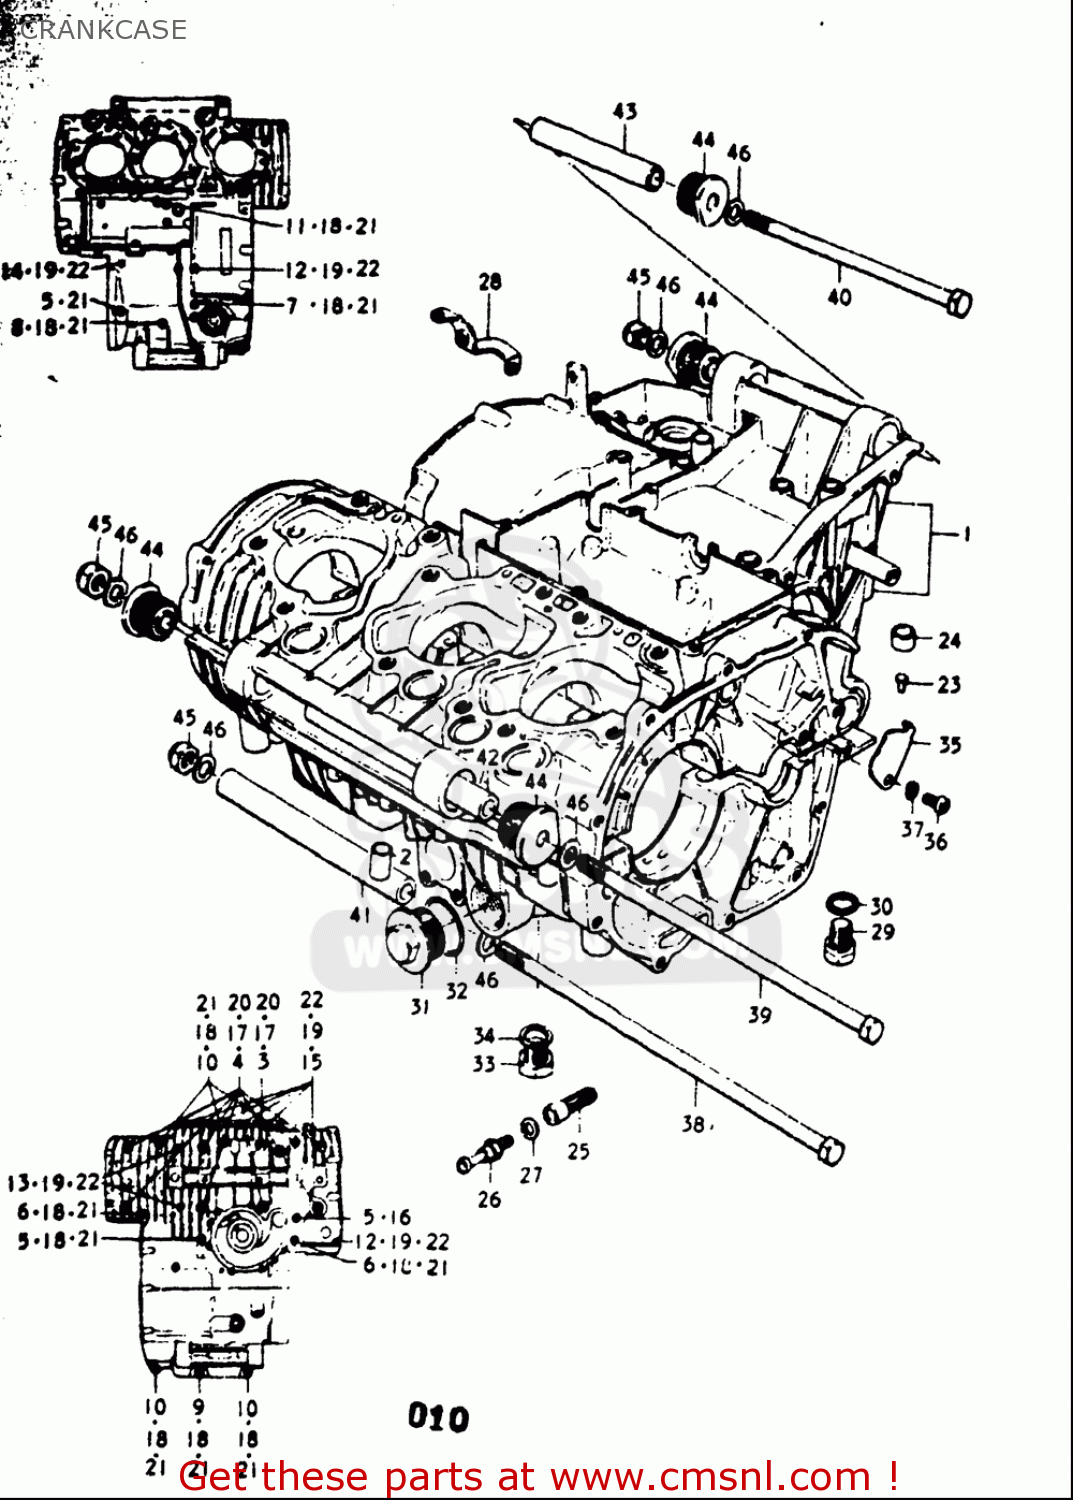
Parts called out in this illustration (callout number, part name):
2	PIN
3	BOLT
6	BOLT
7	BOLT
8	BOLT
9	BOLT
10	BOLT
11	BOLT
12	BOLT 6X110
13	BOLT 6X95 HEXAG
14	BOLT
15	BOLT(6X35)
16	GASKET(8.2X14X1) (NAS)
17	WASHER
18	WASHER
19	WASHER
20	WASHER,LOCK
21	WASHER,LOCK
22	WASHER,LOCK
23	RIVET
24	BUSHING
26	CHECK VALVE,SRIS
27	GASKET(8.2X14X1) (NAS)
29	PLUG
30	GASKET(14X19.2X2) (NAS)
32	O RING(D:1.9,ID:32.7)
33	PLUG(MAGNETO)
34	GASKET(14X19.2X2) (NAS)
36	SCREW
37	WASHER,LOCK
38	BOLT
39	BOLT 10X270
40	BOLT(10X185)
44	BUSH
45	NUT
46	WASHER
